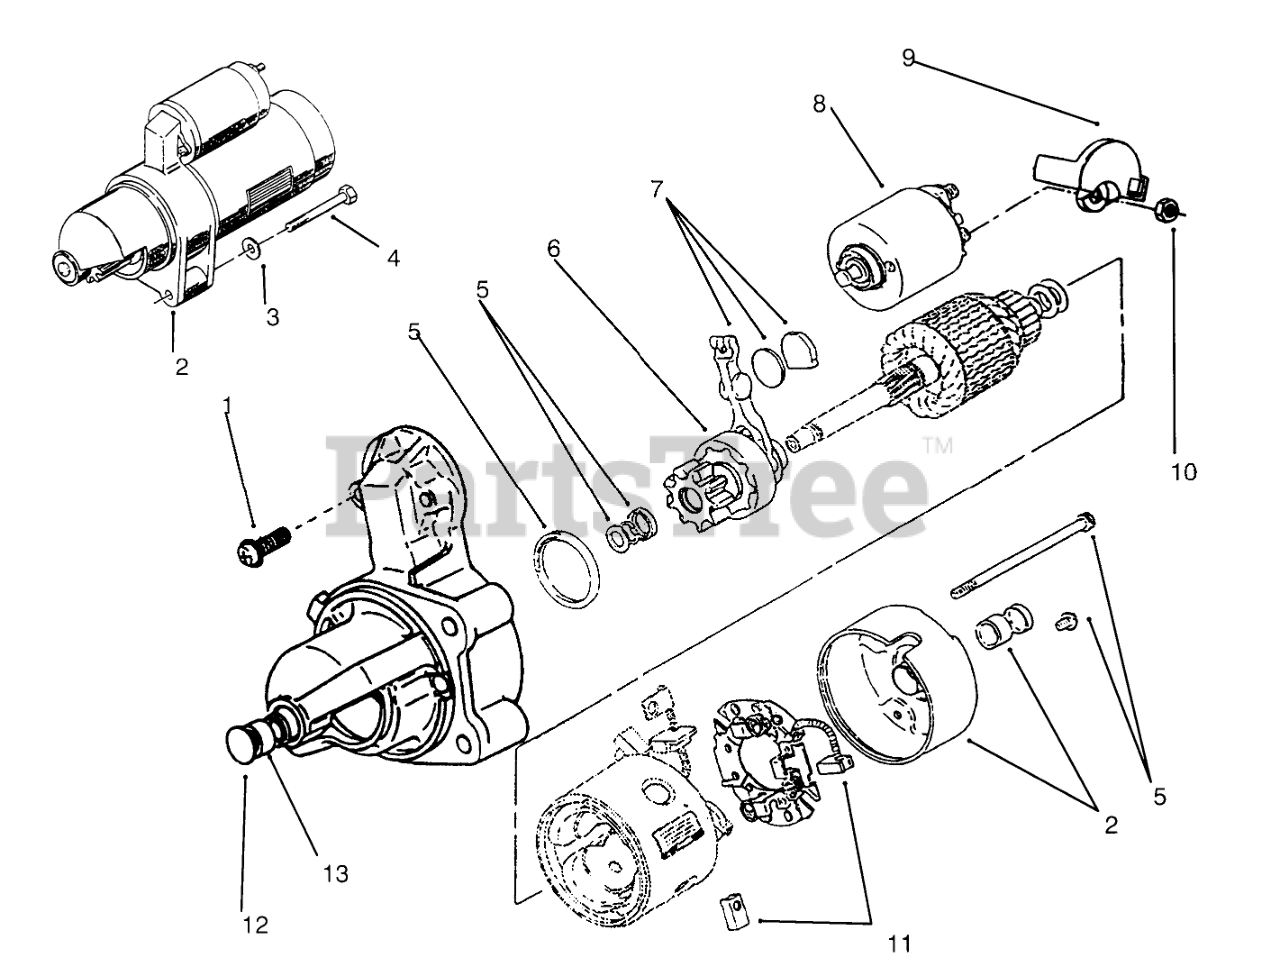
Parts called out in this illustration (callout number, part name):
1	Starter Hdwr Kit (Incl. Solenoid Screws 2], Brush Holder Screws 2], Thru Bolts2], Armature Shims 2], Pinion Stop Collar, & Pinion Retaining Ring)
2	STARTER
3	WASHER
4	SCREW
5	DUST-SEAL KIT
6	Clutch-Starter (Incl. Pinion Gear w/Clutch)
7	Kit-Starter Shift Lever (Incl. Shift Lever, Wear Plate & Rubber Plug)
8	Kit-Starter Solenoid (Incl. Solenoid, Spring, & Plunger)
9	Cap-Starter Solenoid
10	Nut
11	Kit-Starter Brush (Incl. Positive Brush 2] & Negative Brush w/Pigtail)
12	Kit-Bushing (Incl. Front Bushing & Rear Cap w/Bushing)
13	Holder-Starter Brush (Incl. Brush Holder w/Negative Brush)
